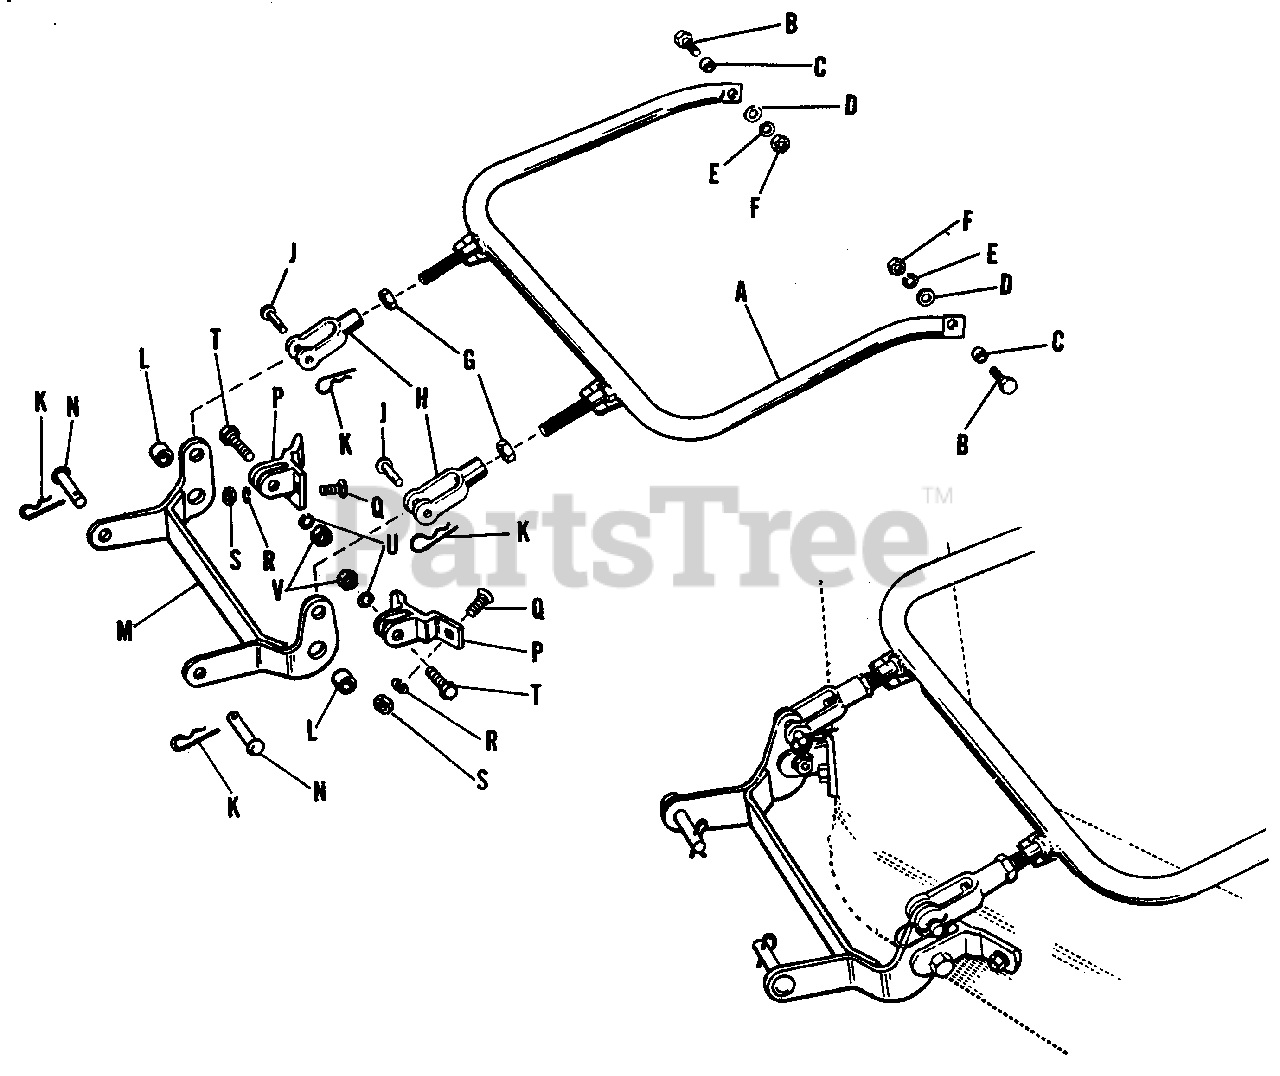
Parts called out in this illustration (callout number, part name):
A	Bail Assembly
B	Capscrew, Hex Hd., 1/2-13 NC x 1 1/4" lg.
D	Washer, Plain, 7/16
E	Washer, Lock, 1/2
F	Nut, Hex, Full, 1/2"-13 NC
G	Nut, Hex, Jam, 1/2"-20 NF
H	Yoke End, Adjusting
K	Clip, Spring
M	Rocker Arm
N	Pin
P	Bracket Assembly, Front
Q	Bolt, Carriage, 3/8"-16 NC x 1"
R	Washer, Lock, 3/8"
S	Nut, Hex, Full, 3/8"-16 NC
T	Capscrew, Hex, 1/2"-13 NC x 1 1/4"
U	Washer, Lock, 1/2" V
V	Nut, Hex., Full, 1/2"-13 NC
